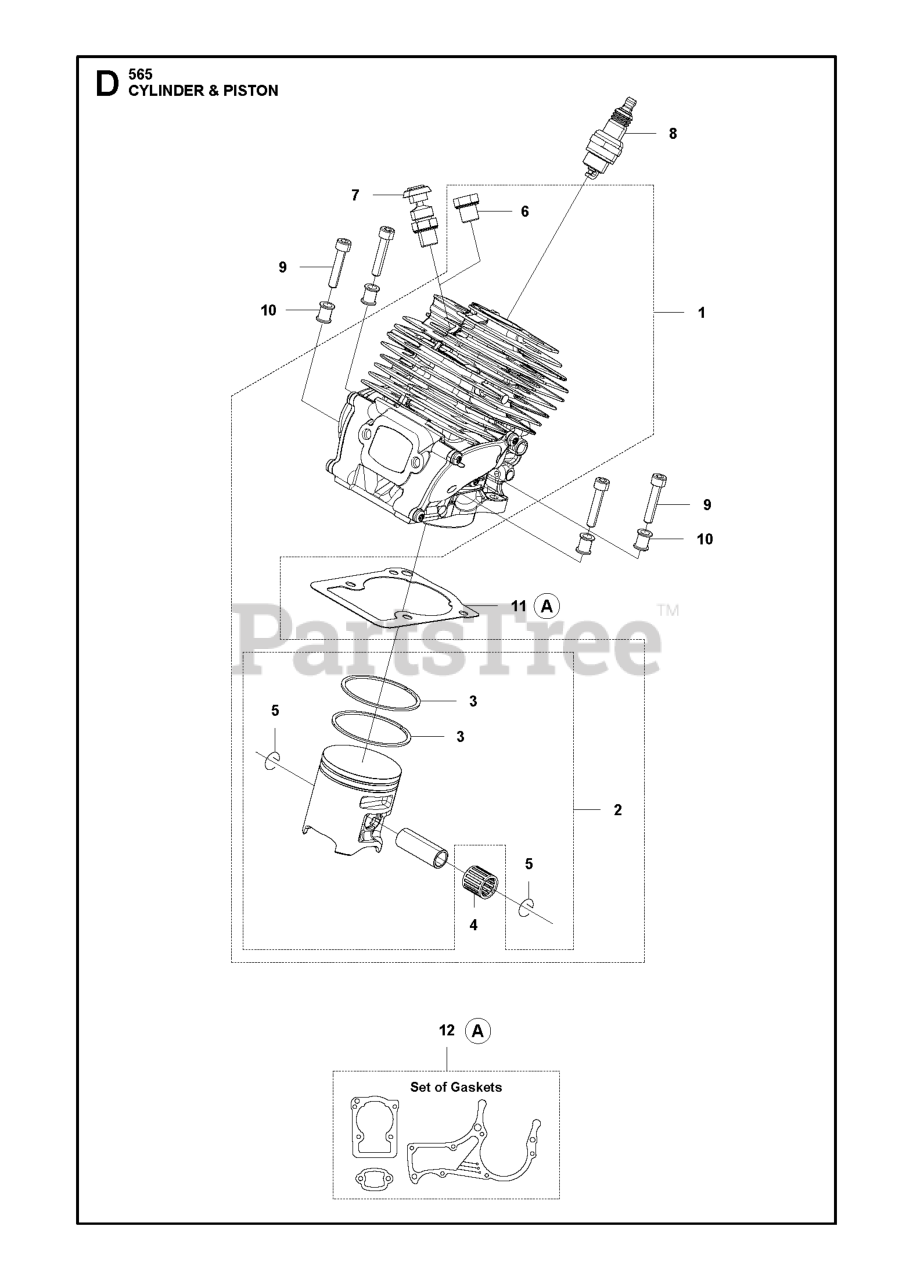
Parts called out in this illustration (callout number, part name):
1	CYLINDER ASSY SPARE PART H565
2	PISTON ASSY D48 M145 (SPARE PA
3	PISTON RING
4	NEEDLE BEARING PISTON PIN 12X1
5	WRIST PIN CLIP
6	CYLINDER PLUG
8	SPARK PLUG M14X1.25 NGK BPMR7A
9	SCREW ITXSCM
10	SLEEVE H572
11	GASKET CYLINDER
12	GASKET KIT H565/H572
